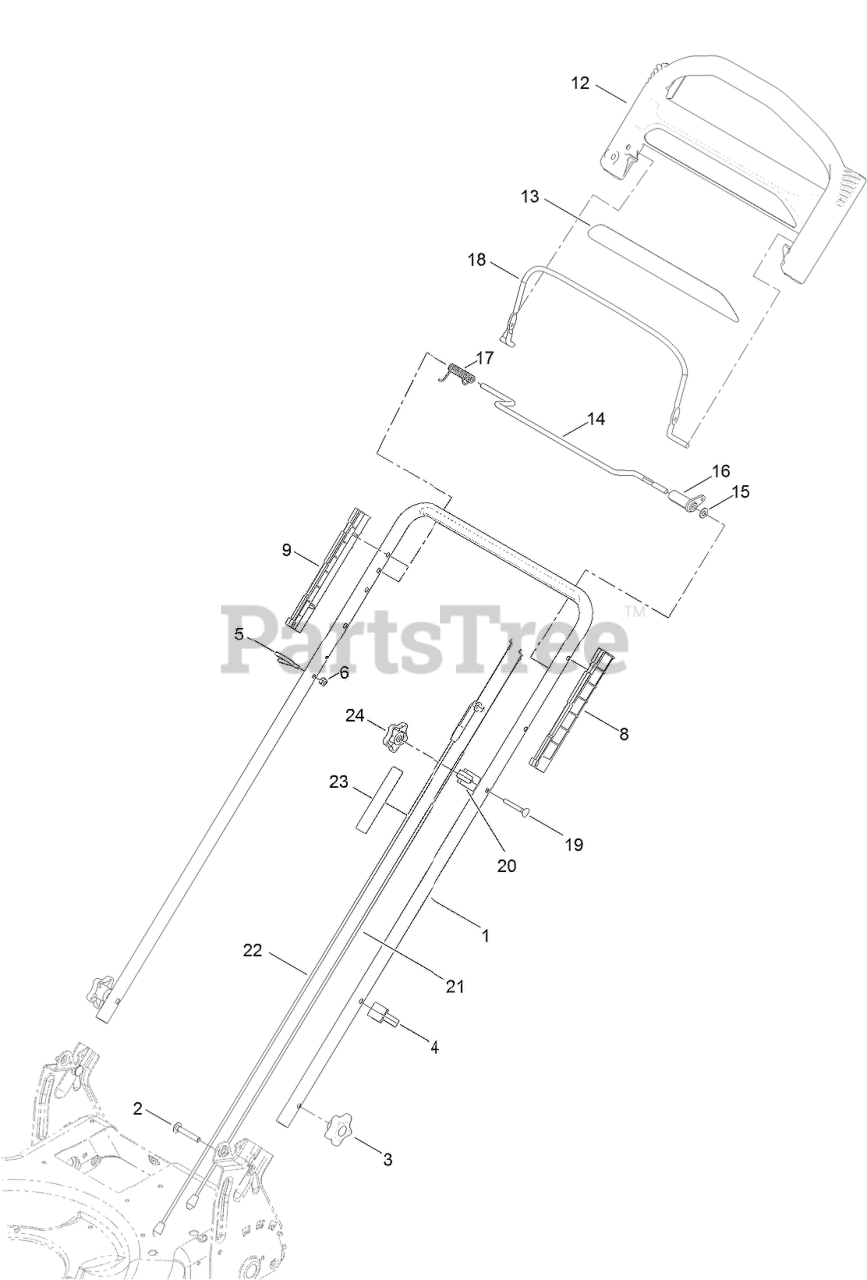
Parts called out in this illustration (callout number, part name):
2	Screw-CARR
3	KNOB-HANDLE
4	GUIDE-CABLE
5	GUIDE-ROPE
6	NUT-LOCK, NI
8	GUIDE-LH
9	GUIDE-RH
12	HANDLE-CONTROL
14	BAR-CONTROL, TRACTION
15	WASHER-PLAIN
16	LEVER-TRACTION
17	Spring-Torsion
18	Bail-Brake
19	SCREW
20	ANCHOR-CABLE
21	CABLE-TRACTION
22	CABLE-BRAKE
23	DECAL-TRACTION, ADJUST
24	KNOB-HANDLE, LOCKING
